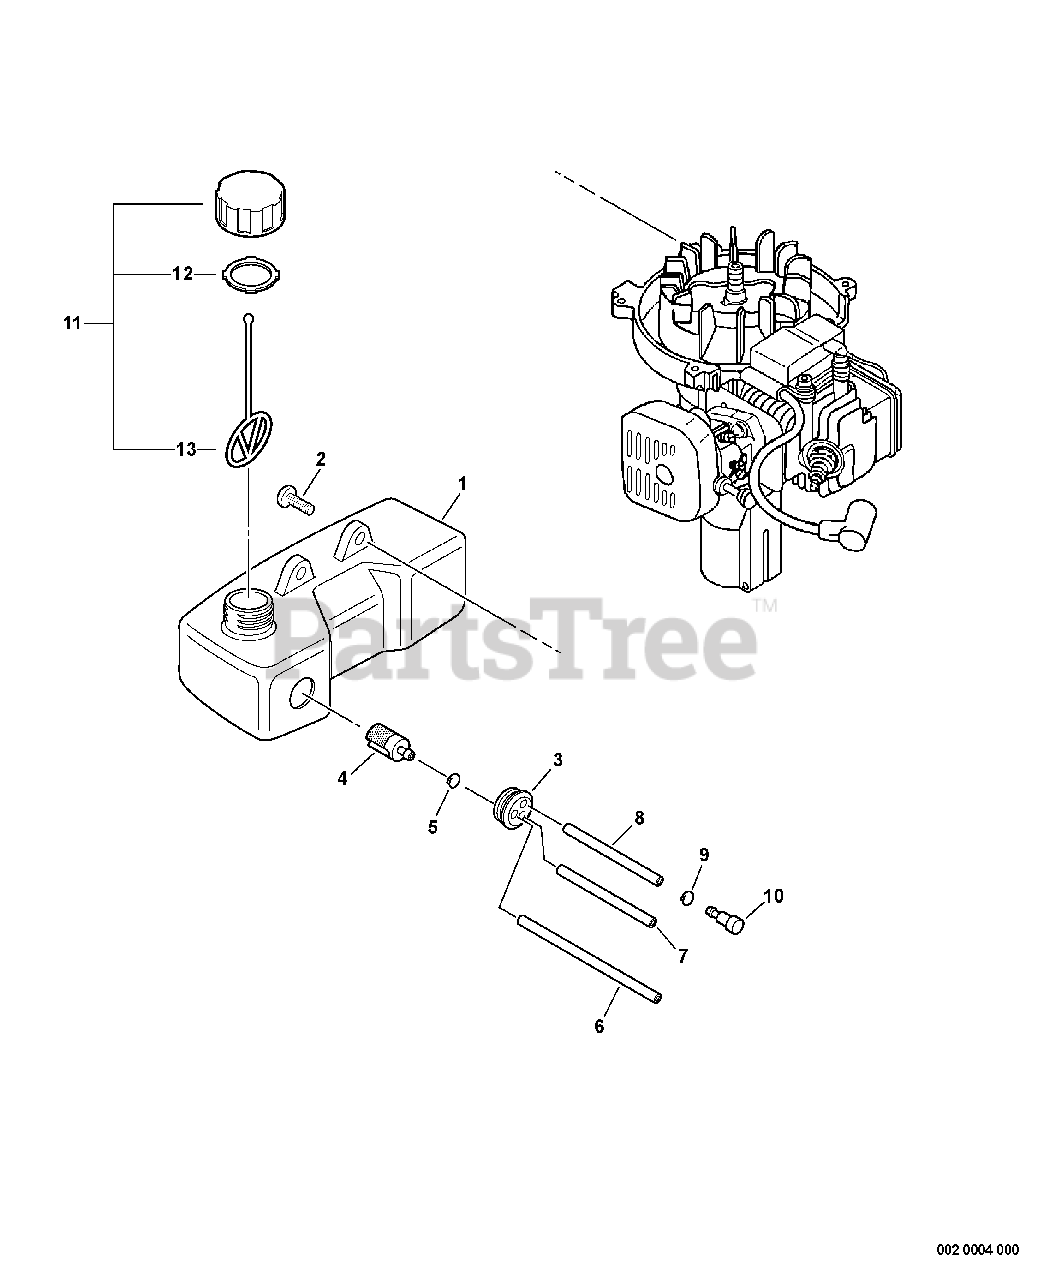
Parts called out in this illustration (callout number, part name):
1	FUEL TANK ASSY
2	SCREW - 5X15
3	GROMMET
4	FILTER, FUEL
5	CLIP - 6
6	PIPE - 3X5X210 -- BLACK
7	PIPE - 3X6X50 -- CLEAR
8	PIPE - 3X5X70 -- BLACK
9	CLIP - 5.5
10	VENT, FUEL TANK
11	CAP ASSY
12	GASKET, CAP
13	CONNECTOR, CAP
